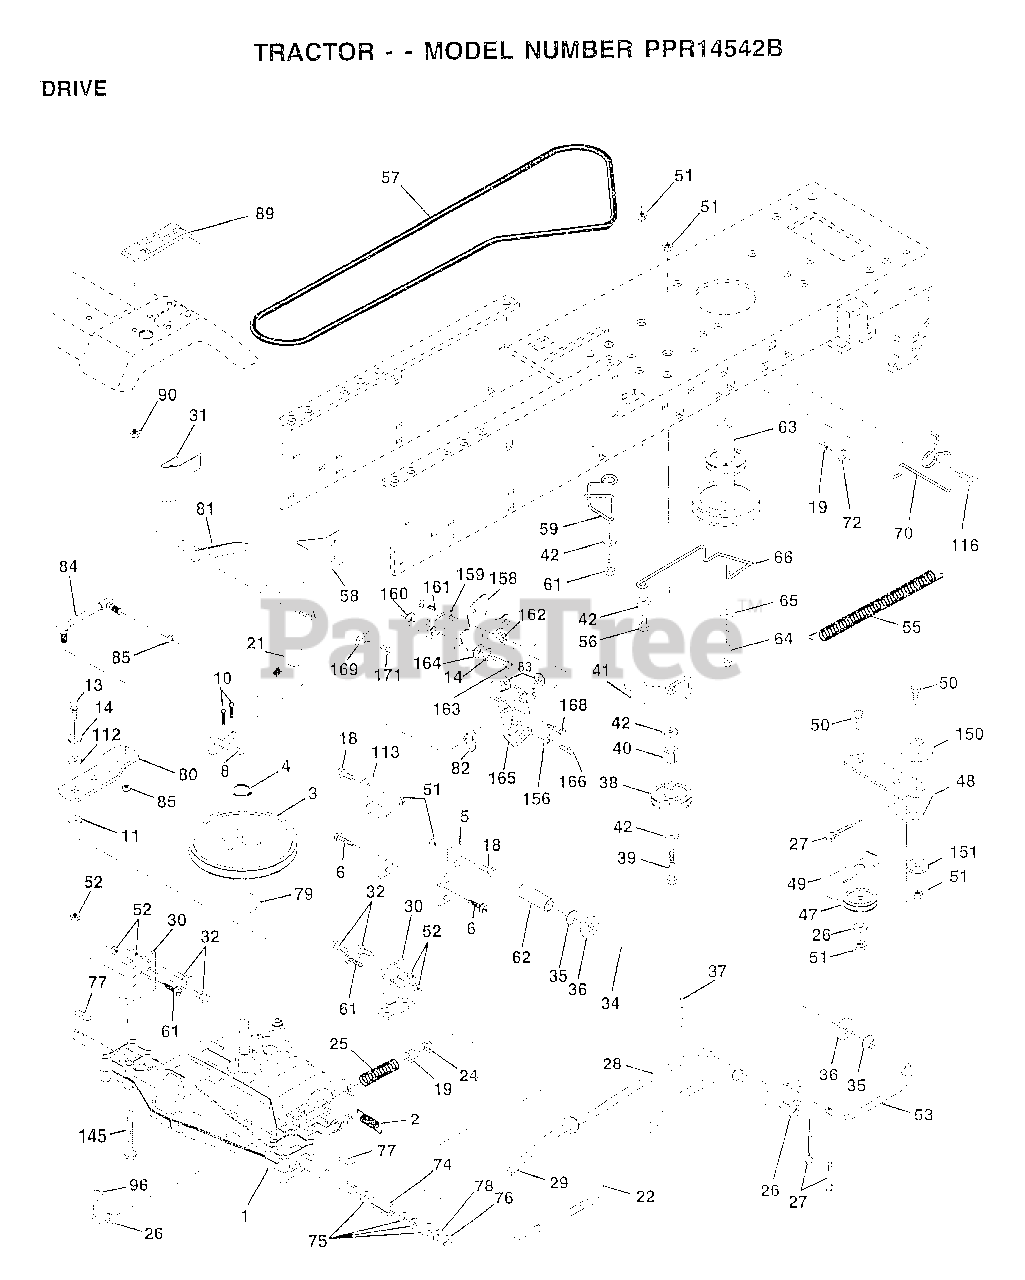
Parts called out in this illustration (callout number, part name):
2	SPRING.BRAKE.RETU
3	PULLEY TRANS
5	STRAP TORQUE
6	SCREW
8	ROD.SHIFT.FENDER.ADJ.LT.CRD
10	PIN COTTER 1/8
11	WASH-SHFT PLT LT
13	BOLT.1/4-28.W/PAT
14	LOCKWASHER
18	BOLT
19	NUT
21	KNOB.DUCKHEAD.1/2
22	BRAKE ROD
24	NUT
25	SPRING ROD LT
26	WASHER
27	COTTER PIN
28	ROD.BRAKE.PARK.LT
29	PLUNGER CAP T
30	TRANSAXLE MTG BKT
31	"KEEPER,BELT LH T"
32	BOLT
34	SHAFT ASM-PEDAL F
35	NYLON BEARING
36	WASHER LT
38	FLAT IDLER PULLEY
39	BOLT
40	SPACER T
41	"KEEPER,BELT.IDLER FLAT"
42	WASHER
48	BELLCRANK.CLUTCH
49	RETAIN BELT
53	"LINK, CLUTCH T"
55	"SPRING, RETURN LT"
58	"KEEPER,BELT RH T"
59	KEEPER BELT CNTSP
61	SCREW
62	PEDAL COVER T
63	PULLEY.ENGINE
64	BOLT
65	LOCKWASHER
66	KEEPER-BELT
70	KEEPER BELT ENG
72	WASHER
74	SPACER AXLE
75	WASHER
76	E-RING LT
77	SQUARE KEY
78	WASHER
80	"ROD,LINK SHIFT"
81	SHAFT.ASM.CROSS
82	"SPRING,TORSION"
83	WASHER
84	LINK.TRANSAXLE
85	NUT.CNT.LOCK.1/4
89	CONSOLE.SHIFT.SLT
90	NUT
96	RETAINER M
112	WASHER LT
113	"STRAP,TORQUE"
116	BOLT RDHD 3/8-16
145	BOLT.HEX.FLGHD
150	BUSHING.BELLCRANK.GRD.DR
151	WASHER
156	WASHER.SRRTD.5/16
157	"BOLT,SHOULDER"
158	BRKT.SHIFT.MOUNT
159	HUB.SHIFT
160	WASHER
161	BOLT T
164	WASHER.5/8X.281X10GA
165	BRKT.PIVOT.LEVER
166	SCREW.5/16-18X5/8
168	BOLT.SHOULDER.5/16-18X.561
169	PLATE.FASTENING
171	SCREW LT
